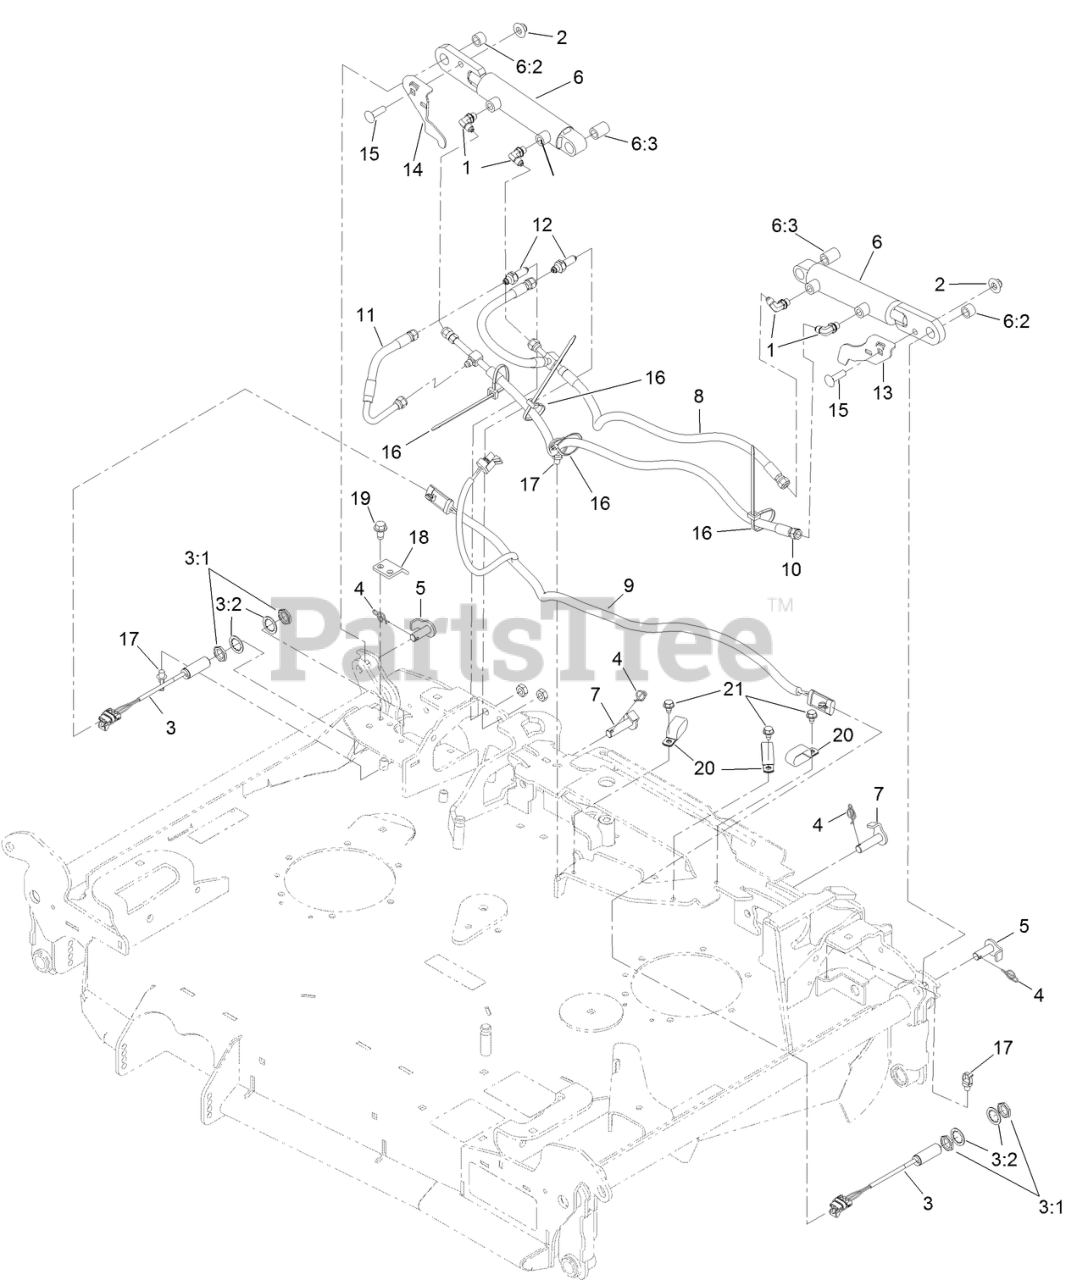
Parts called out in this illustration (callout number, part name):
1	Adapter, 90?
2	NUT-FLANGE, NI
3	PROXIMITY SWITCH ASM
3:1	NUT-HEX
3:2	WASHER-LOCK, INTERNAL TOOTH
4	PIN-COTTER, LOCKING
5	EYE-PIN, CYLINDER
6	DECK FOLD CYLINDER ASM
6:2	BUSHING
6:3	BUSHING
7	BASE-PIN, CYLINDER
8	HOSE ASM
9	HARNESS-WIRE
10	HOSE ASM
11	HOSE ASM
12	FITING-STRAIGHT
13	PLATE-PROXIMITY, LH
14	PLATE-PROXIMITY, RH
15	SCREW-CARR
16	TIE-CABLE
17	CLIP-TIE
18	BRACKET-GUARD, SWITCH (RH)
19	SCREW-HWH
21	SCREW
